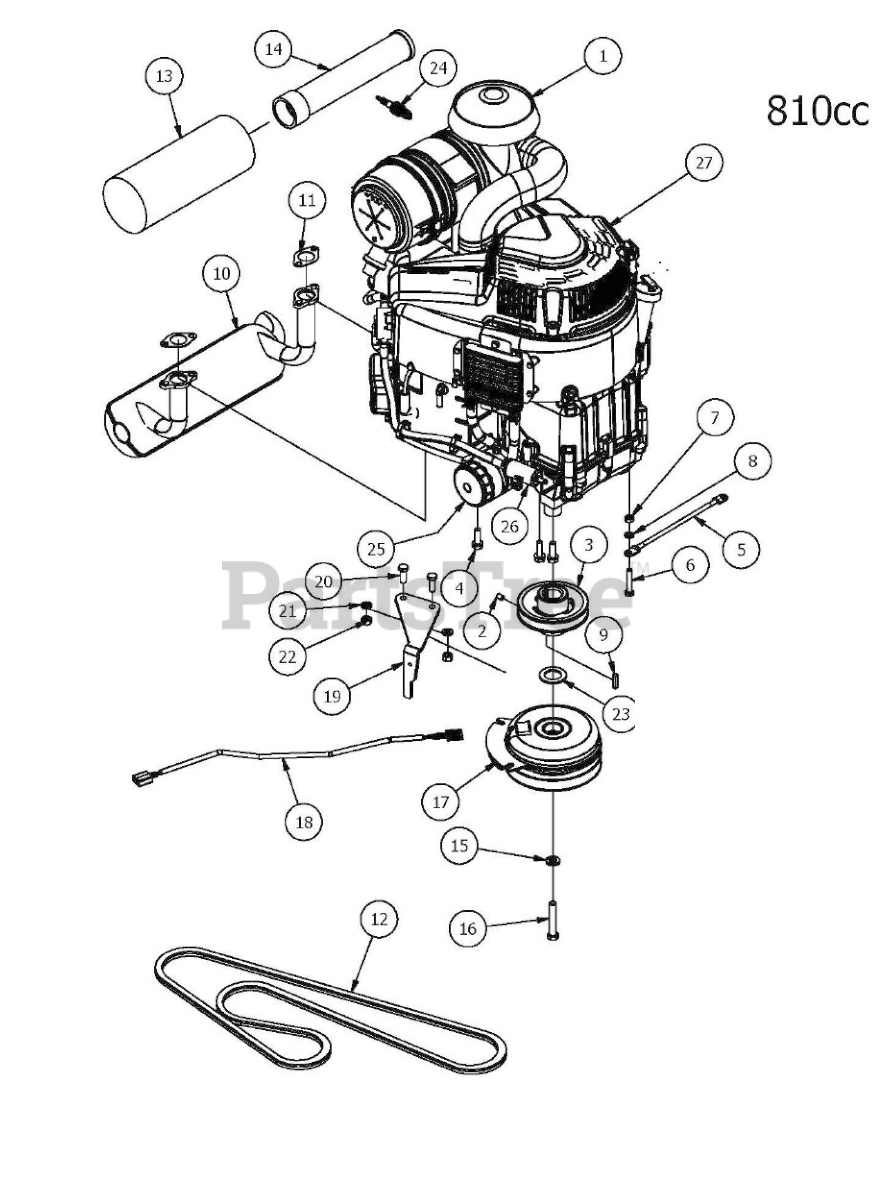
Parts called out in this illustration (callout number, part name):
1	810 Vanguard
2	3/8" Set Screw
3	4 3/4 Motor Pulley
4	3/8 x 1 1/8 bolt
5	Ground Cable
6	5/16" x 1 3/4" Hex Bolt
8	5/16" Lock Washer
9	1/4" x 1" Key
10	Briggs Exhaust
11	Exhaust Gasket
13	Canister Air Filter- Outer
14	Canister Air Filter- Inner
15	7/16" Lock Washer
16	7/16" x 2 1/2" Hex Bolt
17	Clutch Assembly
18	Clutch Pigtail
19	PTO Engager Holder
20	3/8" x 1" Hex Bolt
21	3/8" Lock Washer
22	3/8" Hex Nut
23	1 1/8" Flat Spacer
24	Spark Plug
25	Briggs Oil Filter
26	Universal Inline Fuel Filter
